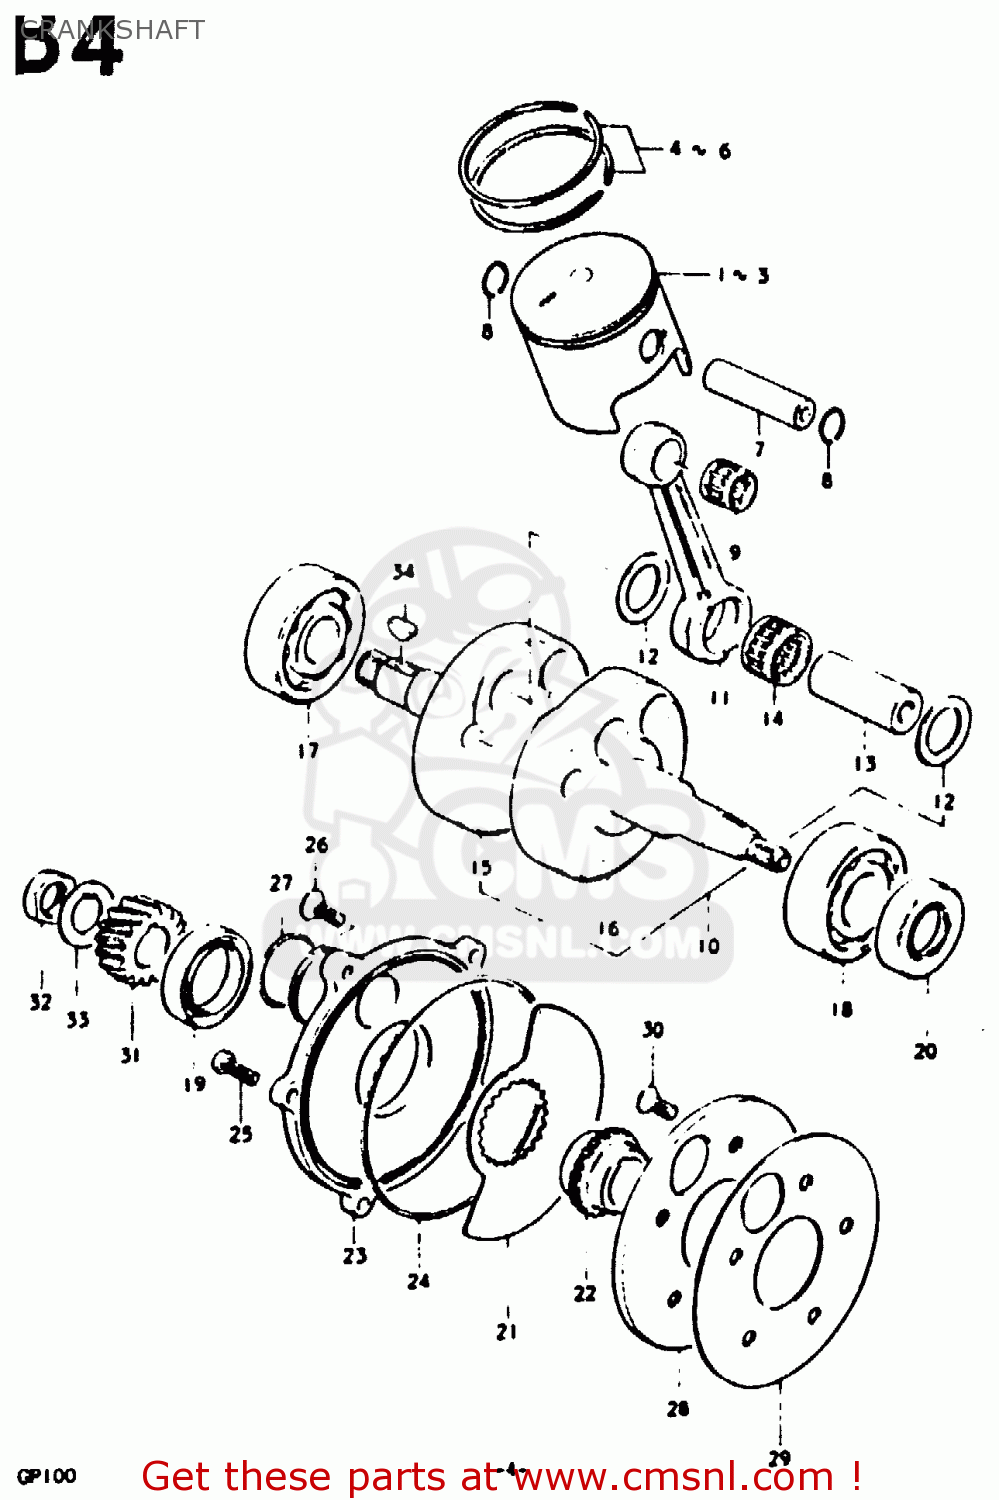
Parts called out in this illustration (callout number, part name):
1	PISTON
2	PISTON (OS:0.5)
3	PISTON (OS:1.0)
4	RING SET,PISTON
5	RING SET,PISTON
6	RING SET,PISTON
7	PIN,PISTON 14MM
8	RING,SNAP 14MM
9	BEARING
10	CRANKSHAFT ASSY
11	CONNECTING ROD
12	WASHER(19X32X1)
13	PIN,CRANK
14	BEARING
15	CRANKSHAFT, RH
16	CRANKSHAFT, LH
17	BEARING
18	BEARING
19	SEAL,OIL(30X44X7)
20	OIL SEAL
21	PLATE,CRANKSHAFT VALVE
22	GUIDE, VALVE
23	SEAT, OUTER VALVE
24	O RING(D:2,ID:108.6)
25	SCREW
26	SCREW
27	O RING(D:2.4,ID:28.7)
28	SEAT,CRANKCASE INNER VALVE
29	GASKET, INNER VALVE SEAT (NAS)
30	SCREW
31	GEAR,PRIMARY DRIVE
32	NUT
33	WASHER
34	KEY
